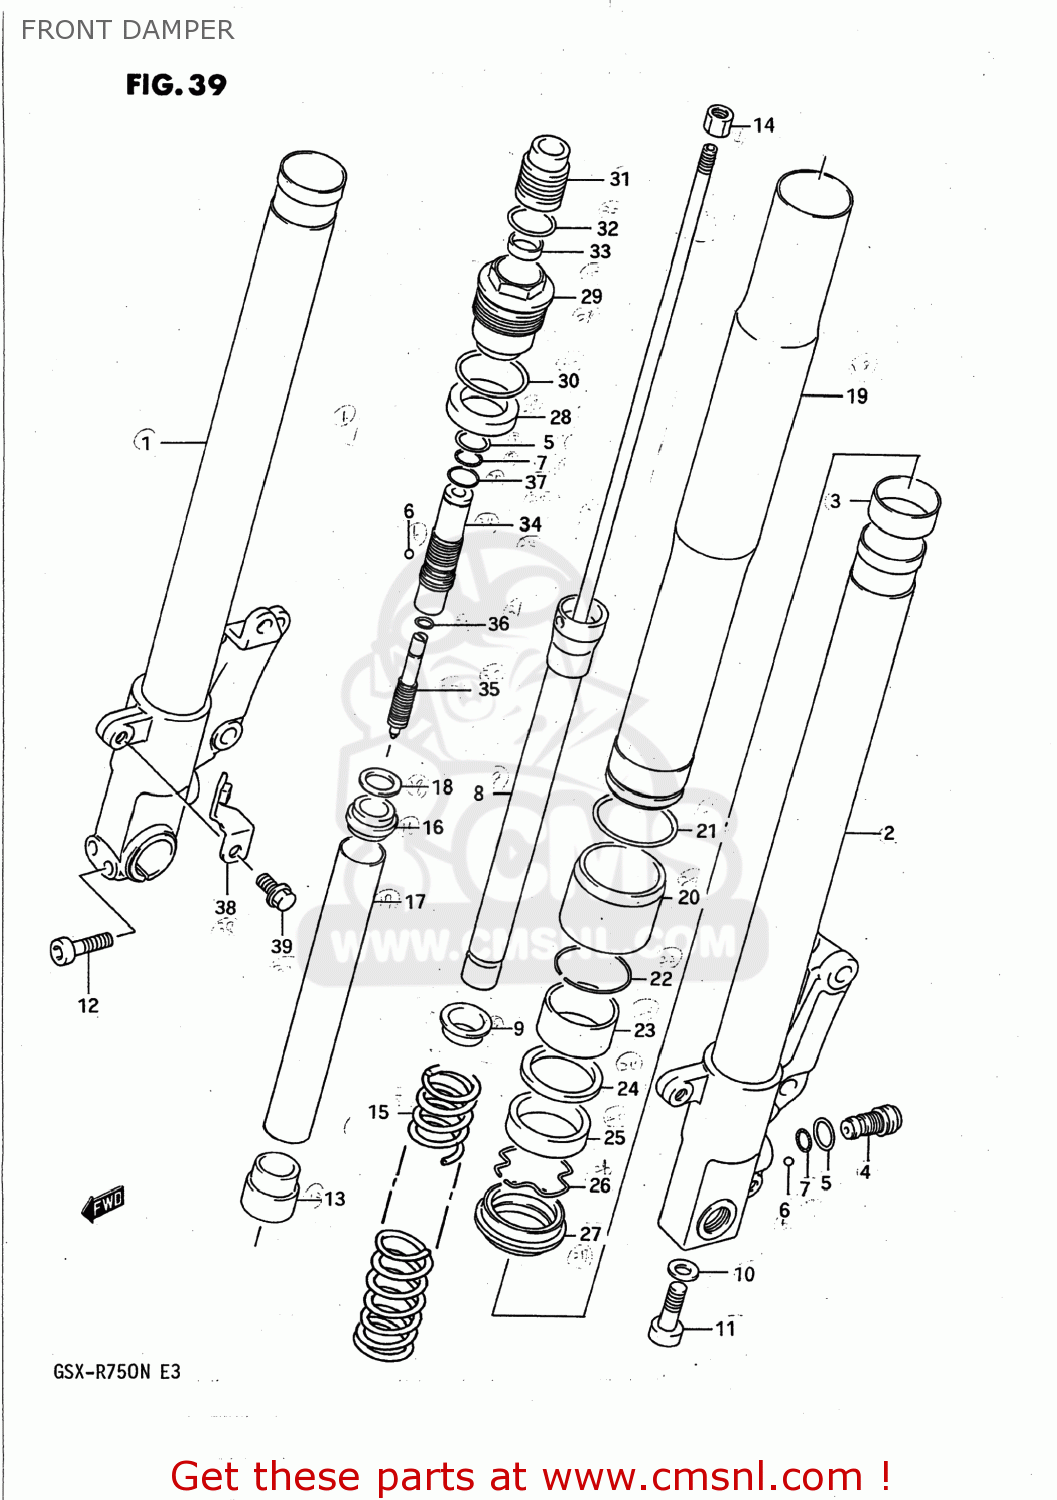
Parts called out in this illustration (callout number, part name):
1	TUBE,INNER,RIGHT
2	TUBE,INNER,LEFT
3	BUSH,SLIDE
4	PIECE,ADJUSTER
5	O RING
6	BALL
7	EXPANDER
8	DAMPER,FRONT
9	PLATE,CENTERING
10	WASHER(10X15X1.5)
11	BOLT
12	BOLT ,8X50
13	JOINT,SPRING LWR
14	NUT
15	SPRING,MAIN
16	GUIDE,SPRING UPR
17	SPACER,SPRING
18	GUIDE,SPRING
19	TUBE,OUTER
20	CASE,OIL SEAL
21	O RING
22	RING,SNAP
23	BUSH,GUIDE
24	SPACER,SEAL
25	SEAL,OIL
26	CIRCLIP,FORK OIL SEAL
27	DUST SEAL,FRONT FORK
28	RUBBER,SEAT
29	BOLT,FORK
30	O RING,FORK BOLT
31	ADJUSTER,SPRING
32	O RING
33	PLATE, SPRING ADJUSTER
34	CASE,ADJUSTER
35	PIECE,ADJUSTER UPR
36	O RING
38	PLATE,FRONT FENDER,LEFT
39	BOLT 8X12
47	RING,STOPPER
